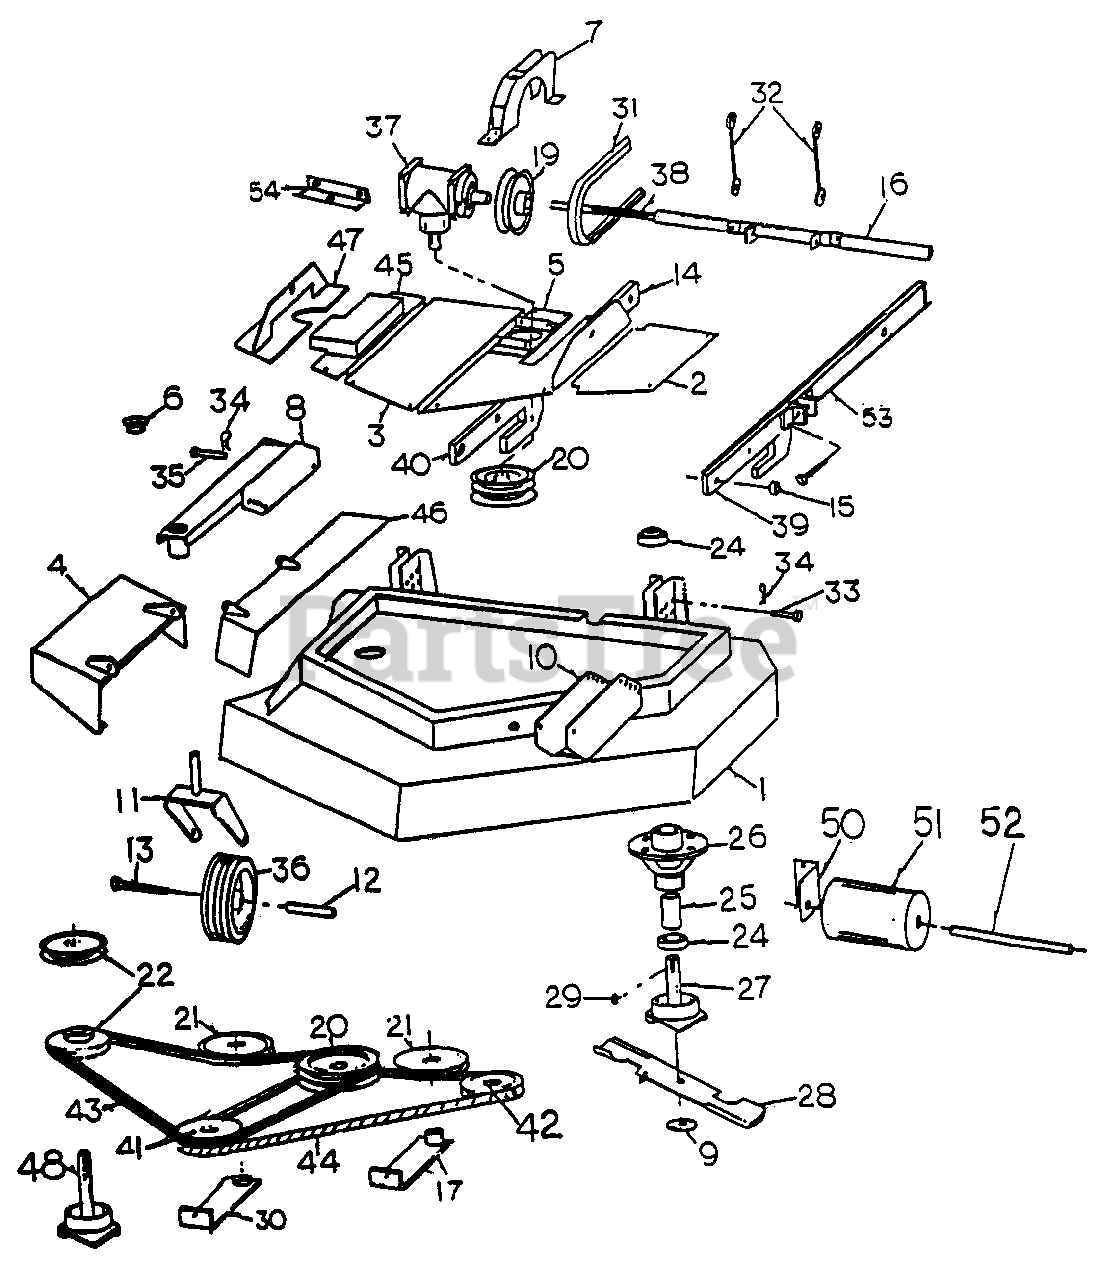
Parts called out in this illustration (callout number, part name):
1	Mower Deck
2	Cover
3	Cover
5	Gear Box Mount
6	Gage Wheel Bushing
8	Gage Wheel Mount
10	Bracket, Gage Wheel Mount
11	Fork, Gage Wheel
12	Axle, Gage Wheel
13	Gage Wheel Bolt
14	Deck Lift Arm Back Adjustable
15	Bushing, Deck Lift Arm
17	Belt Tightener
19	Pulley, Gear Box
20	Pulley, Gear Box
22	Pulley, Spindle
24	Bearing, Spindle
25	Spacer, Spindle
26	Housing, Spindle
27	Shaft, Spindle
29	Key Spindle
30	Belt Tightener
35	Pins, Gage Wheel
38	Cross Bar
39	L.H.1 Deck Lift Arm Front Adjustable
40	RH.1 Deck Lift Arm Front Adjustable
41	Pulley, Double A
42	Pulley, Left Side Spindle
43	Belt, Deck Long
44	Belt, Deck Short
46	Foot Guard Mount
47	Deck Mount
48	Shaft, Spindle Long
50	Rollar Bracket
53	L.H.1 Deck Lift Arm Back Adjustable
54	Gear Box Mount Angle
